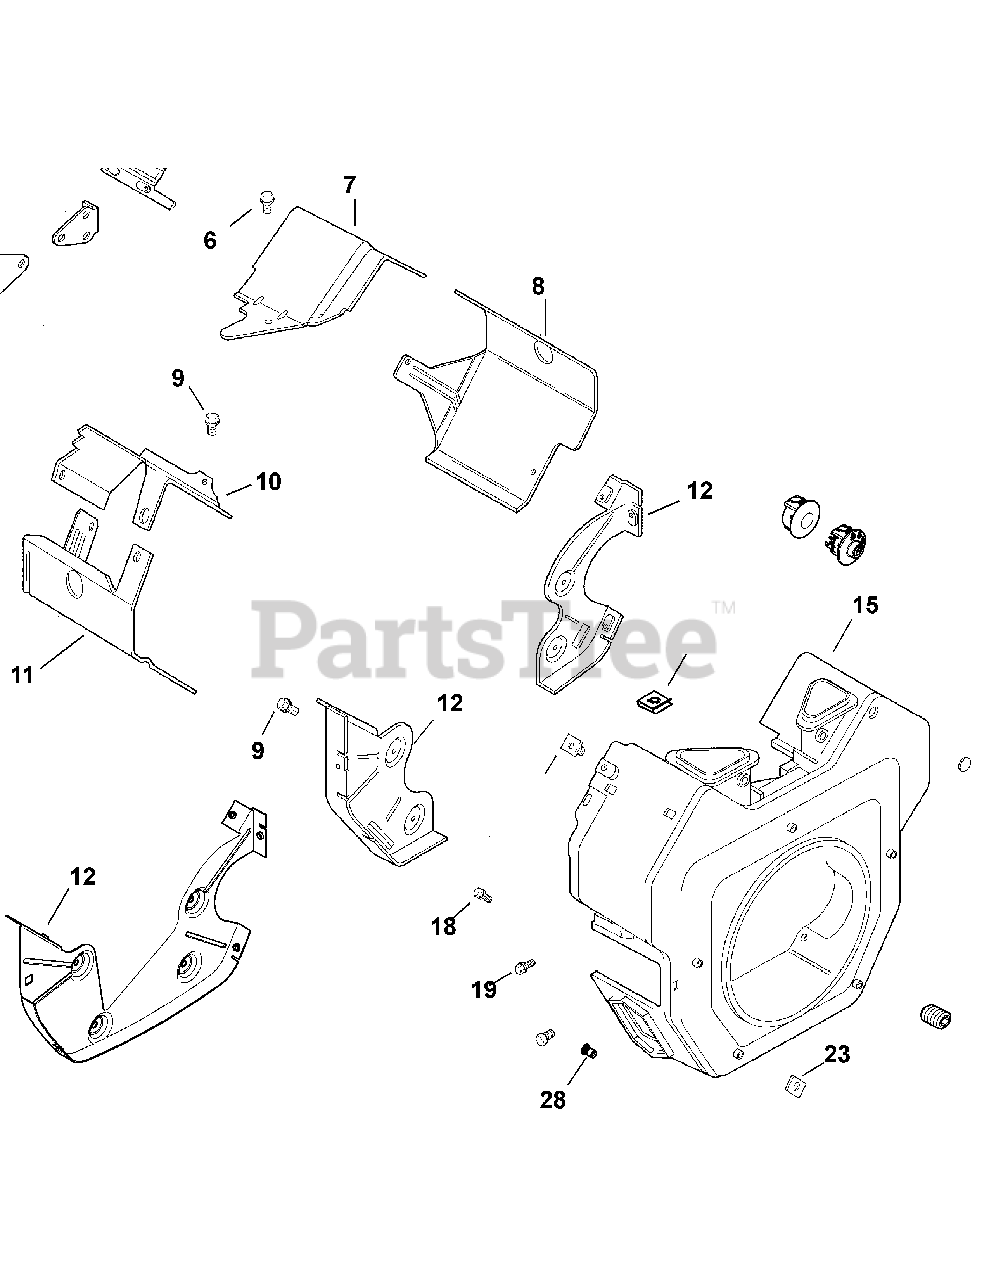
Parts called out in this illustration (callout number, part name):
6	Screw, Thread Forming
7	Baffle, Valley #1 Cyl
8	Kit, Cyl Baffel #1 Side
9	Screw, Thread Forming
10	Baffle, Valley #2 Cyl
11	Kit, Cyl Baffel #2 Side
12	Kit, Backing Plate
15	Kit, Blwr Housing
18	Screw, Thread Forming
19	Screw, Thread Forming
23	Nut, Plastic - Black
28	Insert, Threaded
